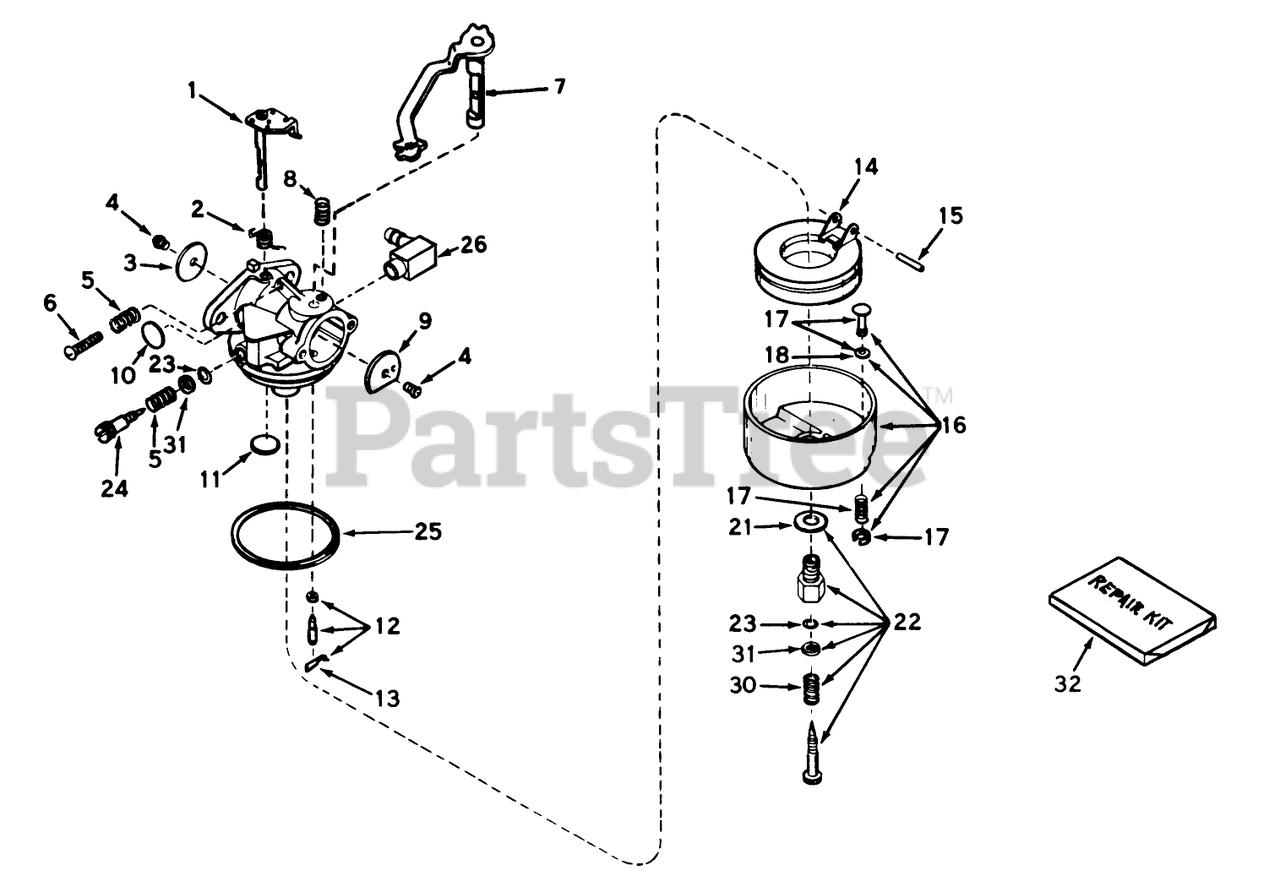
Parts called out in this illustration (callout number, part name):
1	Throttle Shaft and Lever ASM
2	Spring, Throtte Return
3	Shutter-Throttle
4	Screw-Shutter
5	Spring-Tension
6	Screw-Throttle Crack Screw / Idle Speed
7	Shaft Lever Ass-y, Choke
8	Spring-Positioning, Choke
10	Plug-Welch, Idle Mixture Well
11	Plug-Welch, Atmospheric Vent
12	Inlet Needle, Seat Clip Ass-y (Incl. No. 13)
13	Clip-Spring
14	Float,Carburetor
15	Shaft-Float
16	Bowl Drain Assy., Float (Incl. No. 17)
17	Bowl Drain ASM
18	Gasket-Plunger, Drain
21	Washer-Bowl Nut
22	Adjustment Screw Assy., Main (Incl. Nos. 5A, 21 23)
23	ORing
24	Screw, Idle Adj.
25	O Ring-Bowl, Float
26	Fitting, Fuel Inlet
30	Spring
31	Washer
32	Repair Kit (Incl. items marked *)
